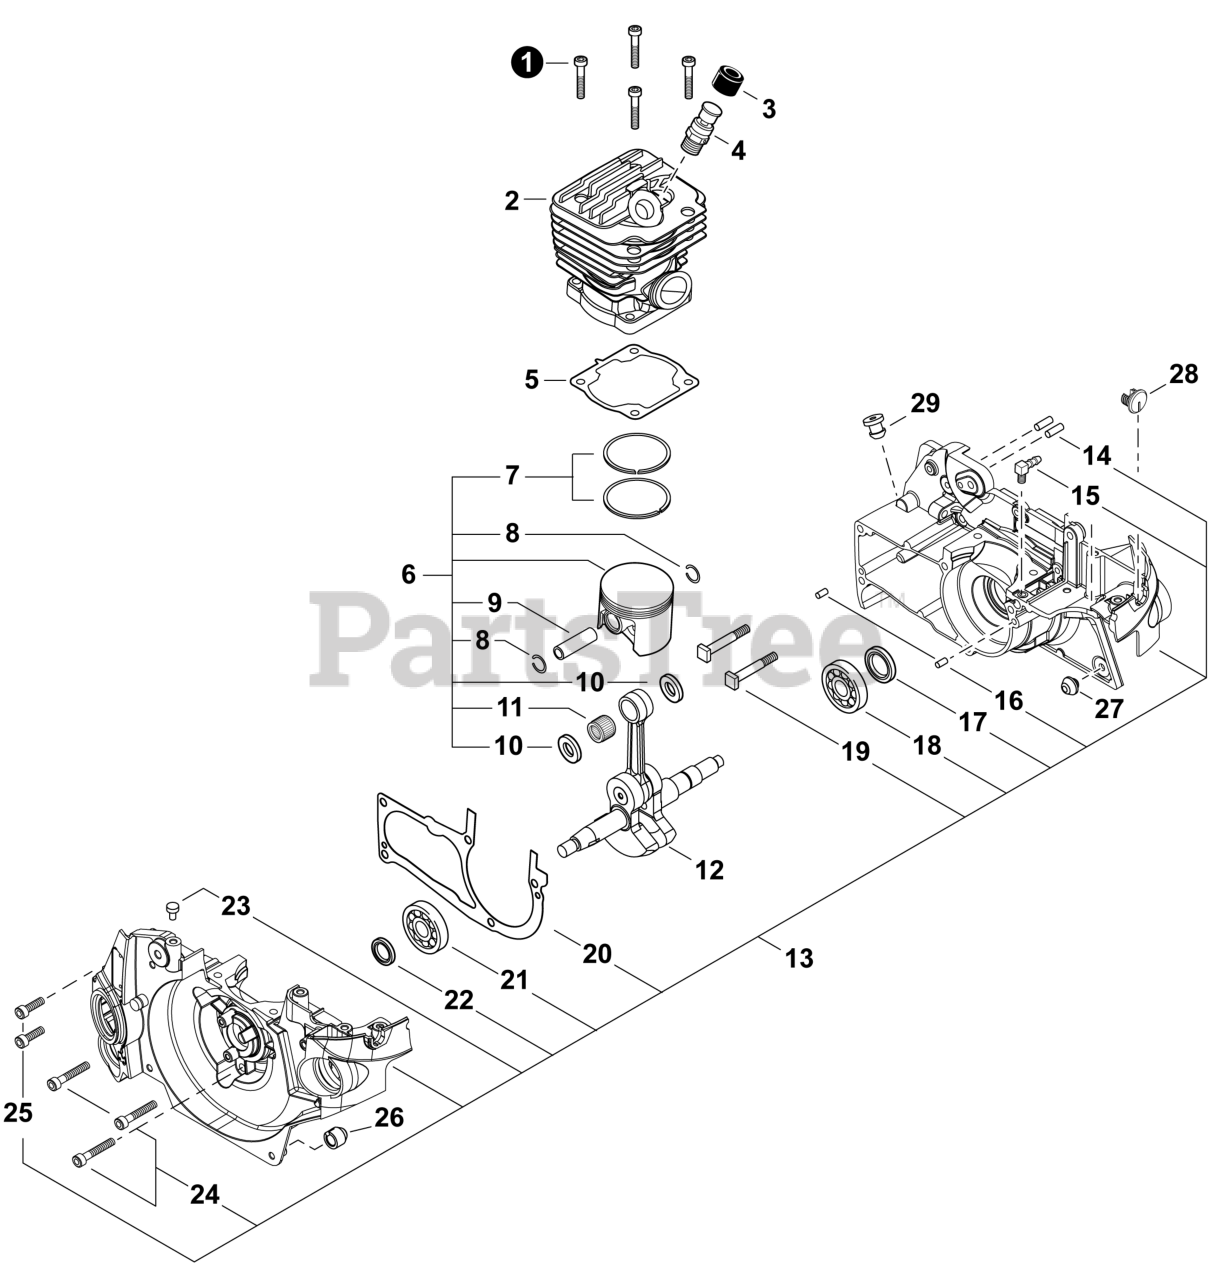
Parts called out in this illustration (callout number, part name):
1	BOLT, ADHESIVE M5x20
2	CYLINDER
3	COVER, DUST
4	VALVE ASSY, DECOMPRESSION
5	GASKET, CYLINDER
6	PISTON KIT
7	RING, PISTON
8	RING, SNAP 11
9	PIN, PISTON 11
10	WASHER, THRUST 11
11	BEARING, NEEDLE 11
12	CRANKSHAFT ASSY
13	CRANKCASE ASSY
14	PIN, LOCATING 4x11
15	CONNECTOR, PIPE
16	PIN, LOCATING 4x8
17	SEAL, OIL 15
18	BEARING, BALL 6202 C3
19	BOLT, STUD 8
20	GASKET, CRANKCASE
21	BEARING, BALL 6201
22	SEAL, OIL 12
23	VENT ASSY
24	BOLT M5x35
25	BOLT M5x18
26	CUSHION M
27	CUSHION
29	GROMMET
